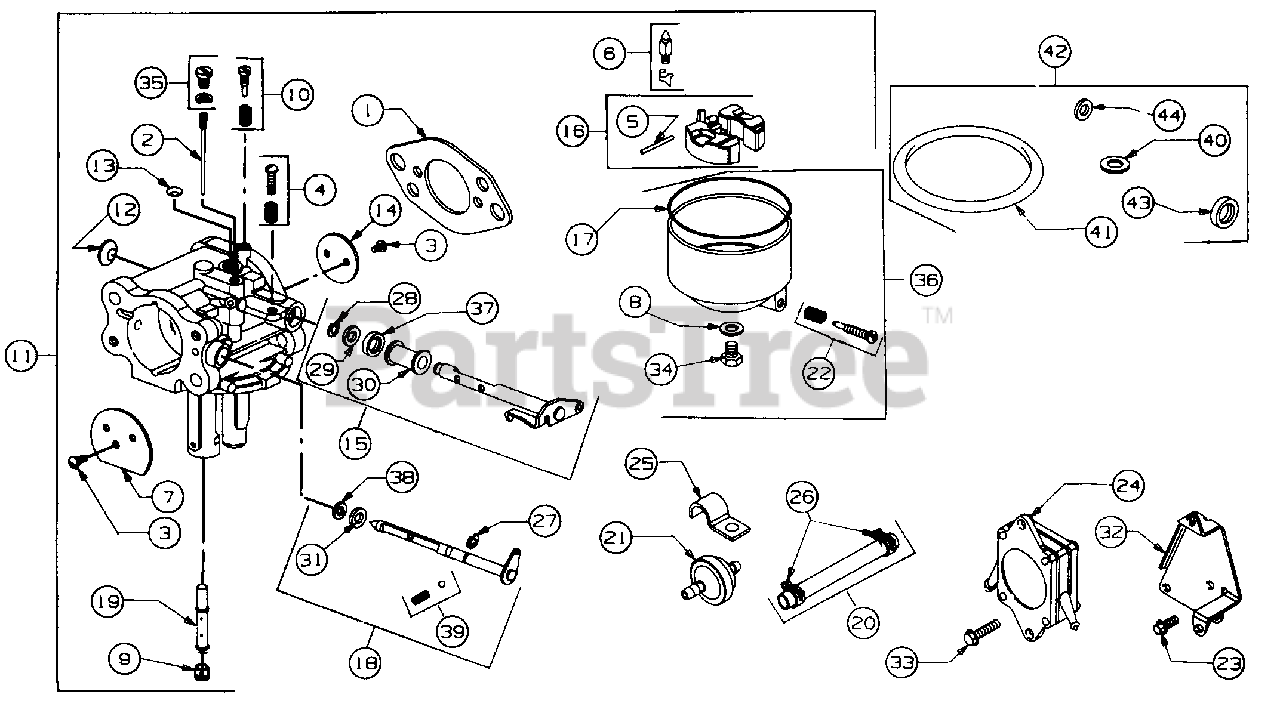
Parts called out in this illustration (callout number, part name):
1	Gasket, Carburetor Mtg
2	Nozzle, Carburetor
3	Screw, Valve Mtg
4	Screw, Throttle Adjusting
5	Pin, Float Hinge
6	Valve, Fuel Inlet
7	Valve, Choke
8	Gasket, Sealing
9	Jet, Main
10	Valve Assy, Carburetor Idle
11	Carburetor Assy
12	Plug, Welch
13	Plug, Welch
14	Valve, Throttle
15	Shaft, Throttle
16	Float Assy, Carburetor
17	Gasket, Bowl Mtg (Sold in kit only)
18	Shaft, Choke
19	Nozzle (Includes Ref No. 9)
20	Hose, Fuel, 11" Lg
21	Filter, Fuel
22	Drain, Carburetor Bowl
23	Screw, Sem
24	Pump, Fuel
25	Clamp, Fuel Hose
26	Clamp, Hose
27	Retainer, Choke Shaft
28	Retainer, Throttle Shaft
29	Collar, Throttle
30	Collar, Throttle
31	Collar, Choke
32	Bracket, Fuel Pump
33	Screw, Mtg
34	Screw, Bowl Mtg
35	Plug & Seal, Carburetor
36	Bowl Assy, Float
37	Seal, Throttle Shaft
38	Seal, Choke Shaft
39	Ball, Choke Locator
40	Gasket, Sealing
41	Gasket, Bowl Mtg
42	Gasket Set, Carburetor
43	Seal, Throttle Shaft
44	Seal, Choke Shaft
